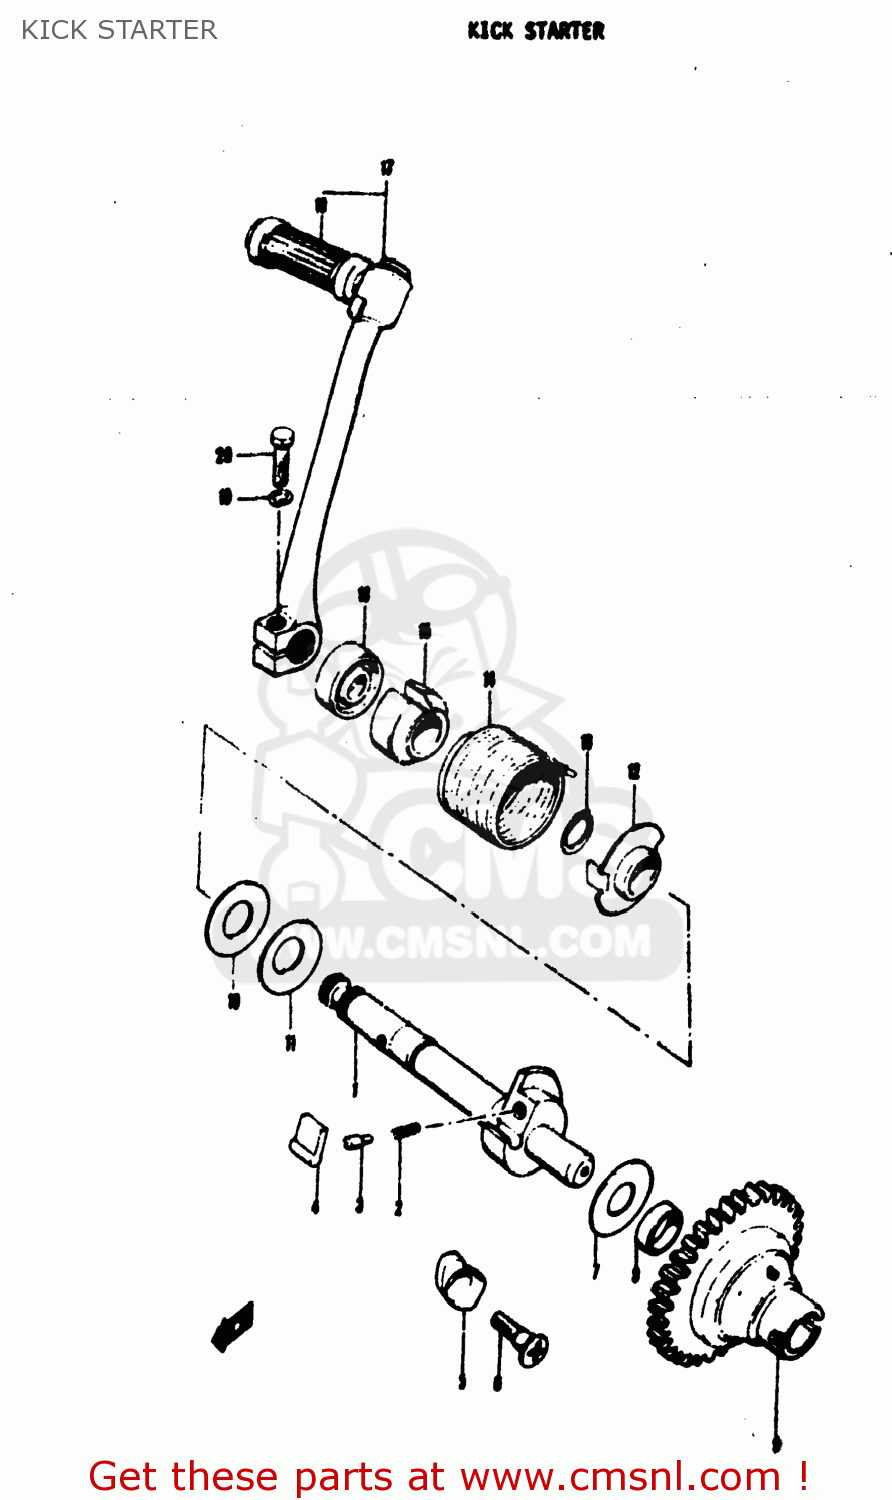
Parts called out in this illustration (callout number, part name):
1	SHAFT,KICK STARTER
2	SPRING
3	PIN
4	PAWL,KICK STARTER
5	LIFTER,KICK STARTER PAWL
6	SCREW(6X19)
7	WASHER
8	OIL SEAL
9	KICK DRIVE GEAR
10	WASHER(14X29X0.8)
11	WASHER
12	HOLDER,KICK STARTER SHAFT SPR
13	CIRCLIP
14	SPRING
15	GUIDE,KICK SHAFT SPRING
16	SEAL,OIL(14X24X6)
17	LEVER ASSEMBLY,KICK STARTER
18	RUBBER,KICK STARTER PEDAL
19	LOCK WASHER
20	BOLT
